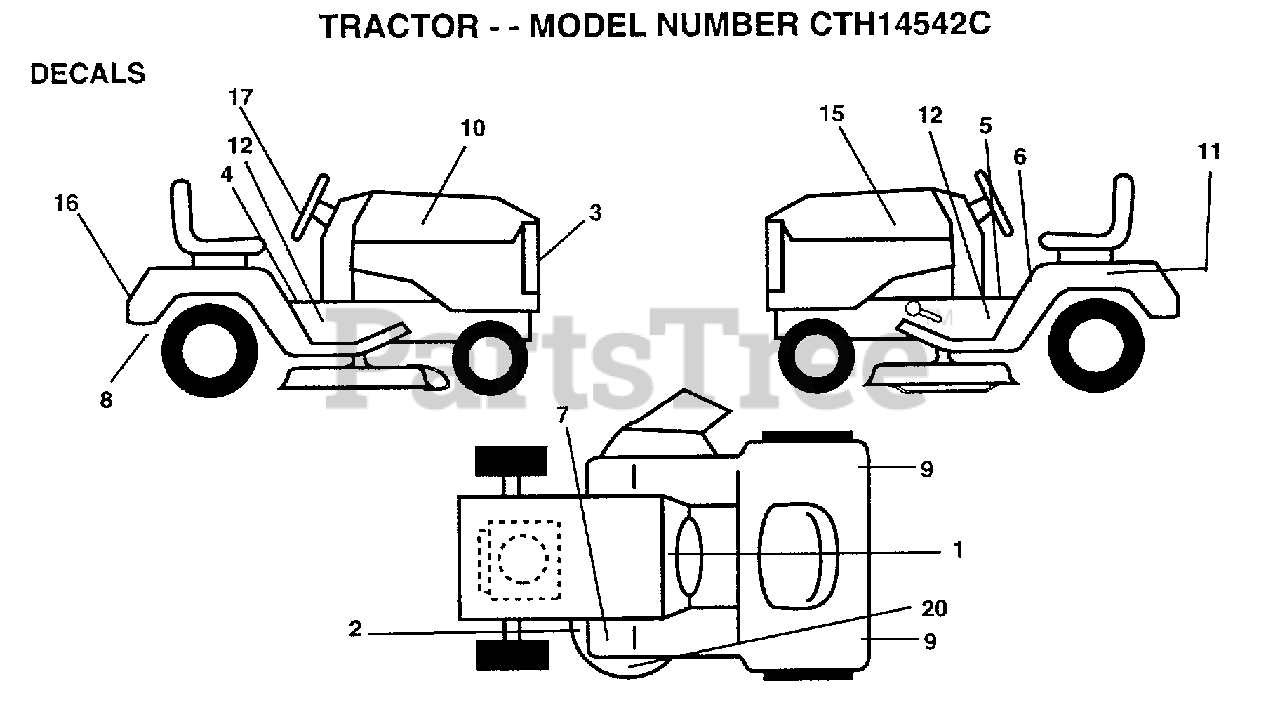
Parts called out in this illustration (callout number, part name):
1	DECAL.DASH.INST.
2	DECAL
3	DECAL.GRILLE.RLY
4	DECAL SADLE HYDRO
5	DECAL BRAK PARK
6	DECAL
8	DECAL DRAWBAR LH
9	REFLECTOR-TAIL YT
10	DECAL.HD.RH.RALLY
11	DECAL.BTRY.DANGER
12	DECAL.CHAS.42.HYD
15	DECAL.HD.LH.RALLY
16	DECAL.FEND.RALLY
17	DECAL.WHL.STR.RLY
